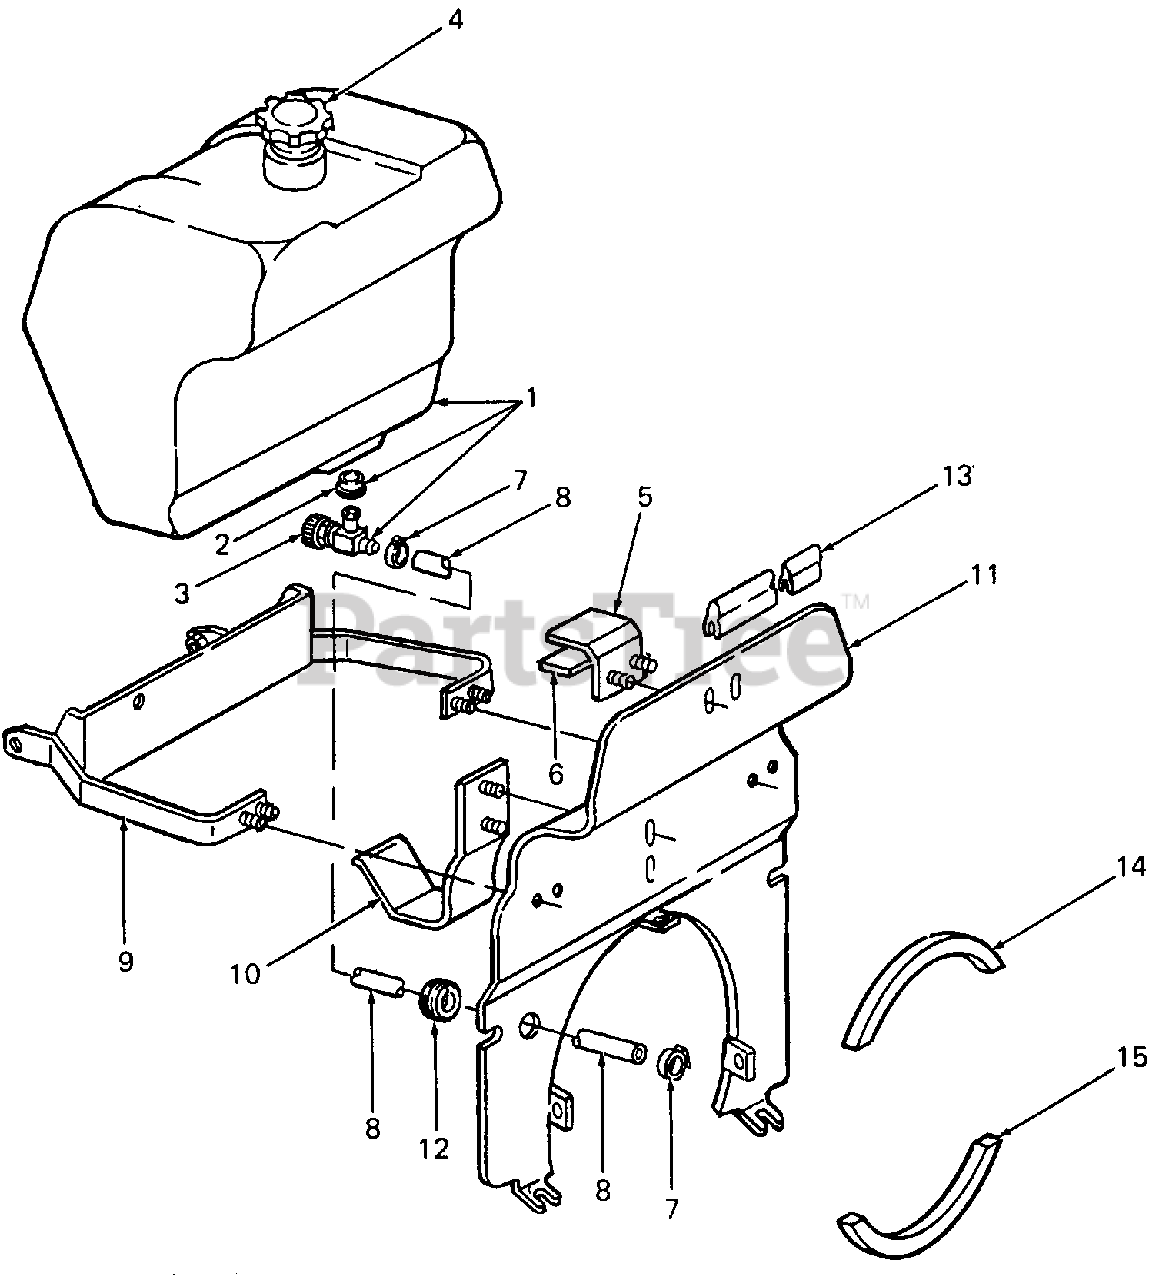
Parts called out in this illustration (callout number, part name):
1	Tank, Fuel
2	Bushing
3	Valve, Shut-off w/Screen
4	Gauge, Fuel Cap
5	Clamp, Fuel Tank
6	Pad, Fuel Tank Adhesive, Loctite, #495
7	Clamp, Hose
8	Line, Fuel - 14 in. Lg
9	Support, Fuel Tank
10	Support, Fuel Tank Bottom
11	Deflector, Heat
13	Seal, Heat Baffle, 56 in. Lg
14	Strip, Foam Gasket Sealing, 27 in. Lg
15	Strip, Foam Gasket Sealing, 17 in. Lg
